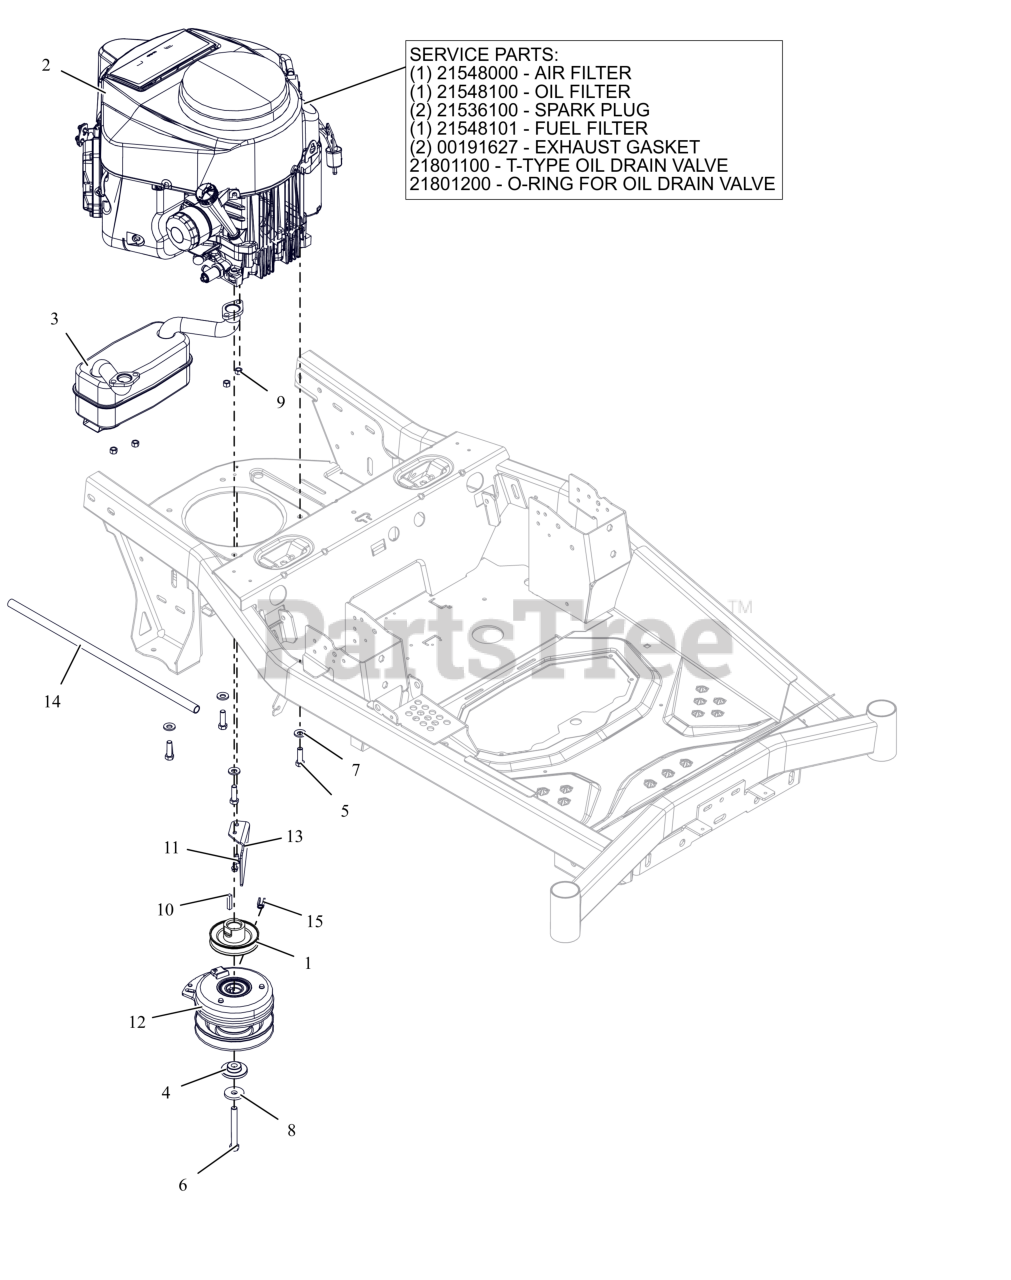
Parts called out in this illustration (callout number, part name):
1	WLDMT, PULLEY 3.75 OD X 1.003 ENGINE
2	ENGINE, KAWASAKI FR651V
2	AIR FILTER, KAWASAKI FR
2	OIL FILTER, KAWASAKI FR
2	PLUG, SPARK
2	FUEL FILTER-KAWASAKI FR
2	GASKET, MUFFLER S/O
2	T-TYPE OIL DRAIN VALVE
2	O-RING FOR OIL DRAIN VALVE
3	MUFFLER - KAWASAKI
4	BSHG-FLG .469X1.06X.574X2.0
5	BLT, HEX .38-16X1.25 G5 ZCC NT
6	BLT, HEX 0.4375-20X3.5 G8 ZCC NT
7	WASHER, 3/8" SPRING DISC
8	WASHER, 7/16" SPRING DISK
9	NUT-LK-TOP-FLG M8 ZCC
10	KEY-SQ .25 X 1.25 X .25 SAE
11	SCR-TAP .25-20X.50 HWH ZCC
12	CLUTCH- WARNER IXR-18211
13	BRKT- CLUTCH STOP
14	HOSE, OIL DRAIN
15	BSHG, CLUTCH
